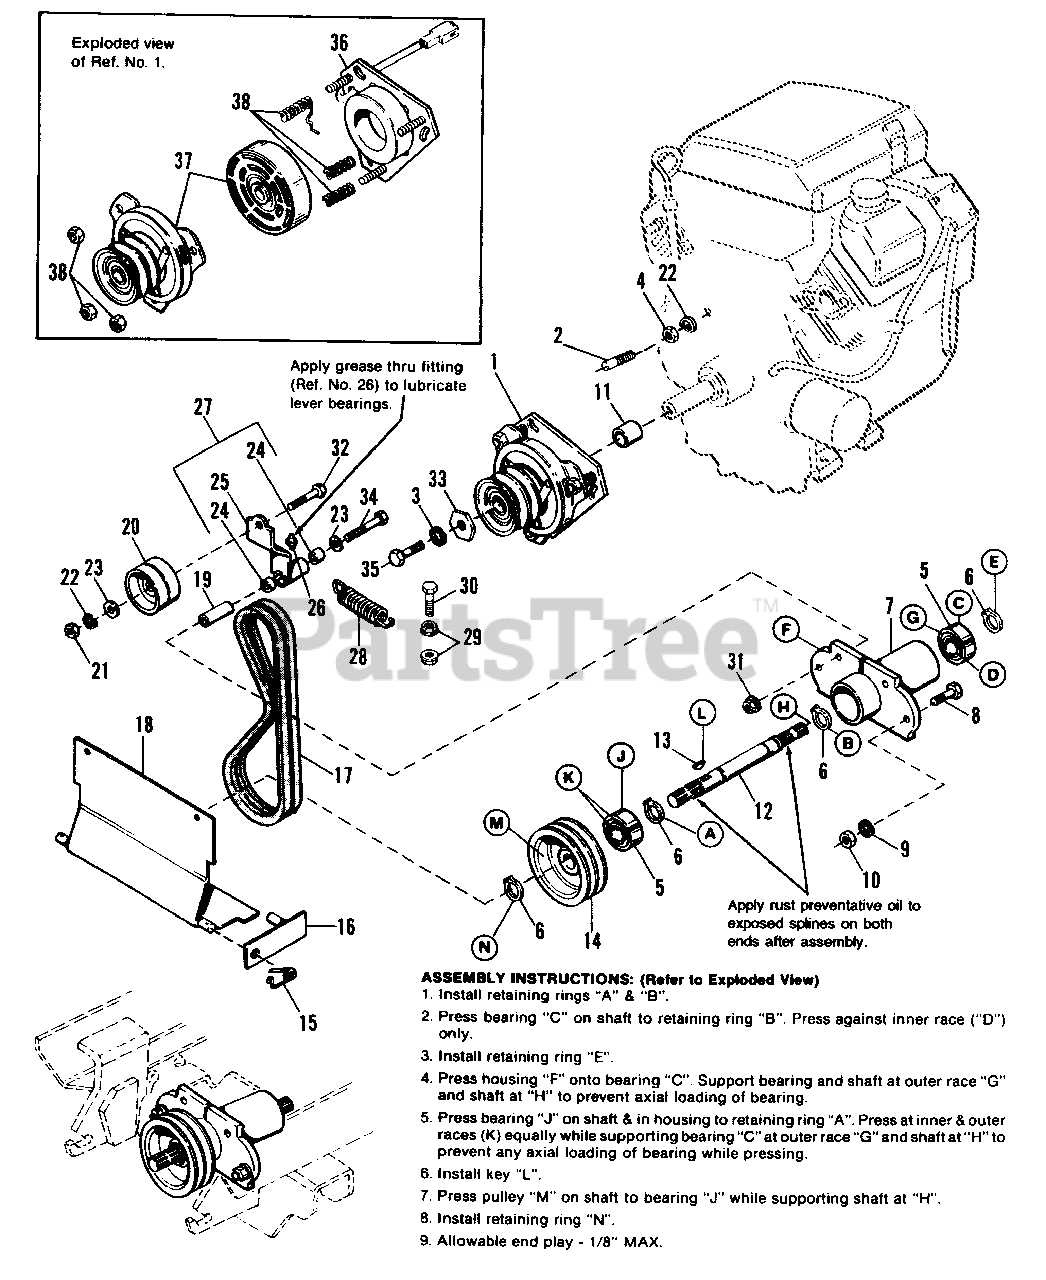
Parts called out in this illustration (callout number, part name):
1	CLUTCH, Electric (Incl. Ref. Nos. 36, 37 & 38 )
2	STUD, Clutch, Torque
3	LOCKWASHER, 7/16
4	NUT, Hex Jam, 3/8-16
5	BEARING, Ball, 1-3/16 x 2-7/16 x 5/8
6	RING
7	HOUSING & PLATE ASSY.
8	CAPSCREW, Hex Hd., 1/2-13 x 1-1/4, Gr. 5
9	LOCKWASHER, 1/2
10	NUT, Hex, 1/2-13
12	SHAFT, Spline, PTO
13	KEY, Hi PRO, 1/4 x 3/4
14	PULLEY, PTO Drive
15	CLIP, Pin, Safety
16	LINK & PIN ASSY., Guard
17	BELT SET, PTO Drive (Matched Set of 2)
18	GUARD ASSY.
19	SPACER, 3/8 x 5/8 x 1-3/4
20	PULLEY, Idler, 3-1/4 Dia.
21	NUT, Hex, 3/8-16
22	LOCKWASHER, 3/8
23	WASHER, 13/32
24	BUSHING, Idler Arm
26	FITTING, Grease
27	IDLER ARM ASSY. (Incl. Ref. Nos. 24 & 25)
28	SPRING, Tension
29	NUT, Hex, Flange Whizlock, 3/8-16
30	CAPSCREW, Hex Hd., 3/8-16 x 1-3/4
31	NUT, Hex, Flange, 3/8-16
32	SCREW, Hex Hd., 3/8-16 x 2
33	WASHER, Hex
34	SCREW, Hex Hd., 3/8-16 x 2-1/2, Gr. 5
35	SCREW, Hex Hd., 7/16-20 x 2.0, Gr. 5
36	FIELD ASSEMBLY
37	ROTOR ASSEMBLY & ARMATURE ASSEMBLY KIT
38	ACCESSORY KIT (Nut & Springs)
